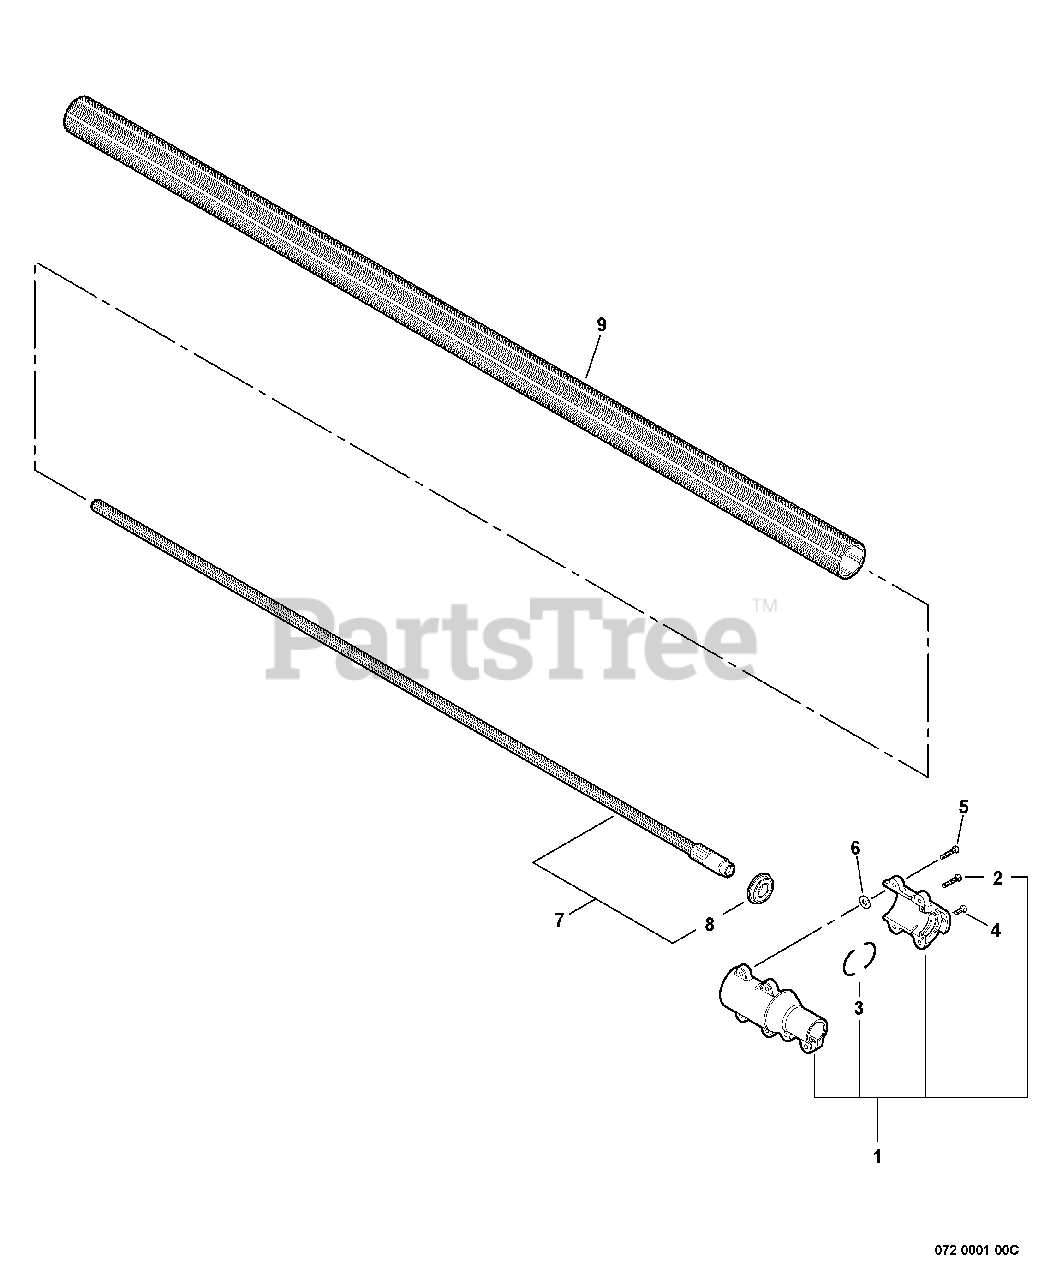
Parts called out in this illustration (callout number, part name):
1	COUPLING ASSY, LOWER
2	BOLT 5×20
3	CUSHION
4	BOLT 5×14
5	BOLT 5×20
6	WASHER 5
7	DRIVESHAFT ASSY, LOWER
8	BEARING, BALL 15×32×9
9	PIPE, MAIN - ORANGE
